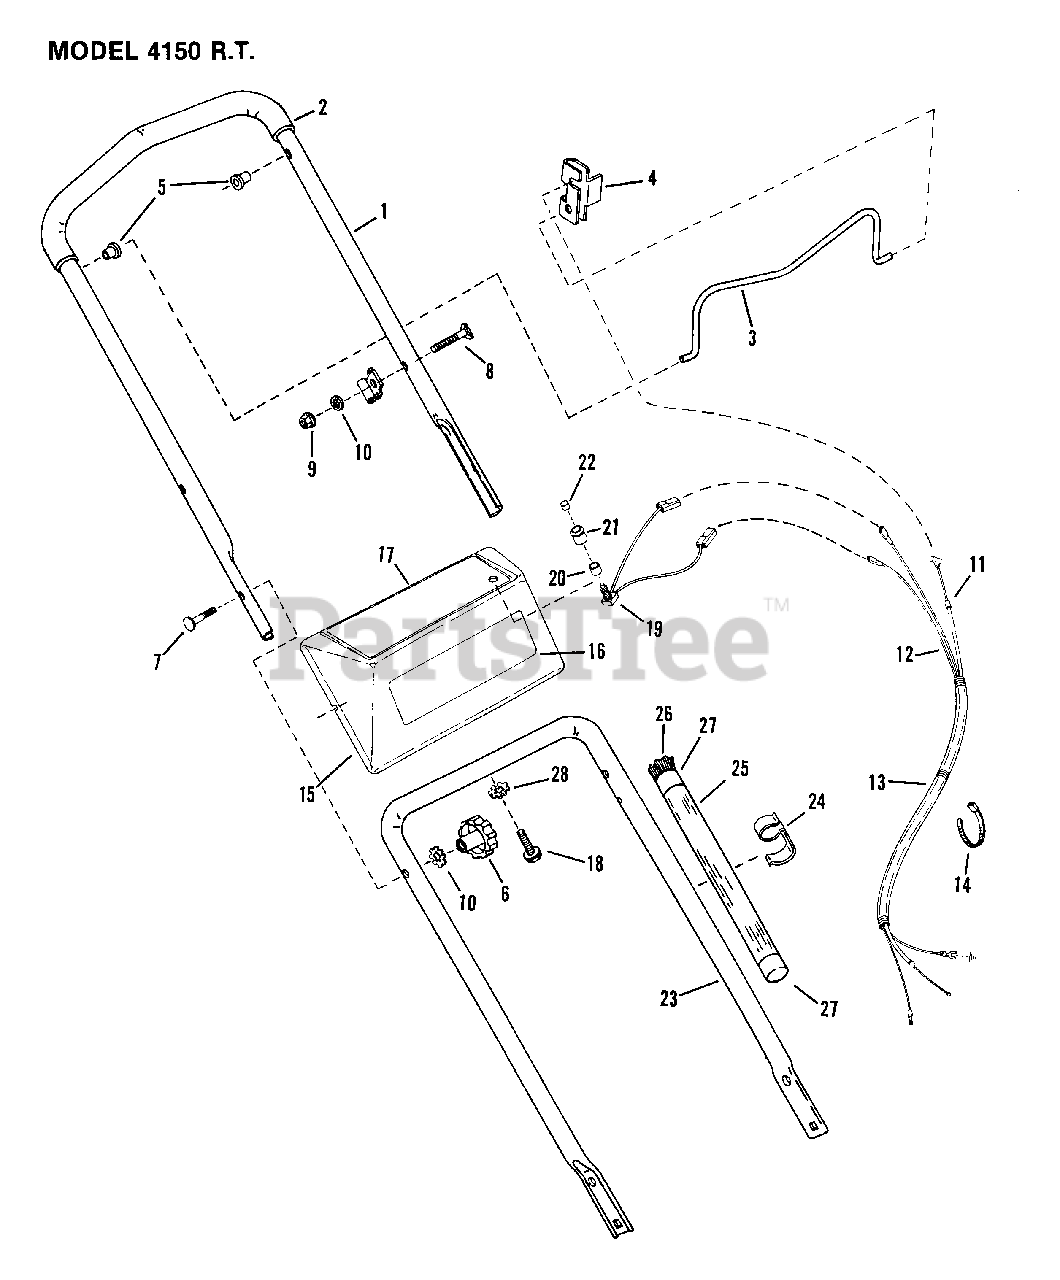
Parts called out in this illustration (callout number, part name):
1	HANDLE, Upper
2	GRIP, Foam
3	BAIL, Throttle
4	CLIP, Throttle
5	BUSHING, Bail
6	KNOB, 5/16-18 Plastic
7	BOLT, 5/16-18 x 2" Curved Head
8	BOLT, 1/4-20 x 1-1/2" Curved Head
9	NUT, 1/4-20 Hex Flange Lock
10	WASHER, 5/16 Int./Ext. Tooth Lock
11	ASSEMBLY, Throttle Cable
12	HARNESS, Wire
13	SHEATH, Harness
14	TIE, Cable
15	ASSEMBLY, Panel/Label
16	LABEL, Model
17	LABEL, Instruction
18	SCREW, 5/16-18 x 5/8" Self-Tapping
20	SPACER, Switch
21	BEZEL, Switch
22	CAP, Switch
23	HANDLE, Lower
24	CLIP, Wire
25	TUBE, Plastic
26	LINE, .130 DIA. (50 PIECES)
27	CAP, Tube
28	WASHER, 5/16 Int./Ext. Tooth Lock
